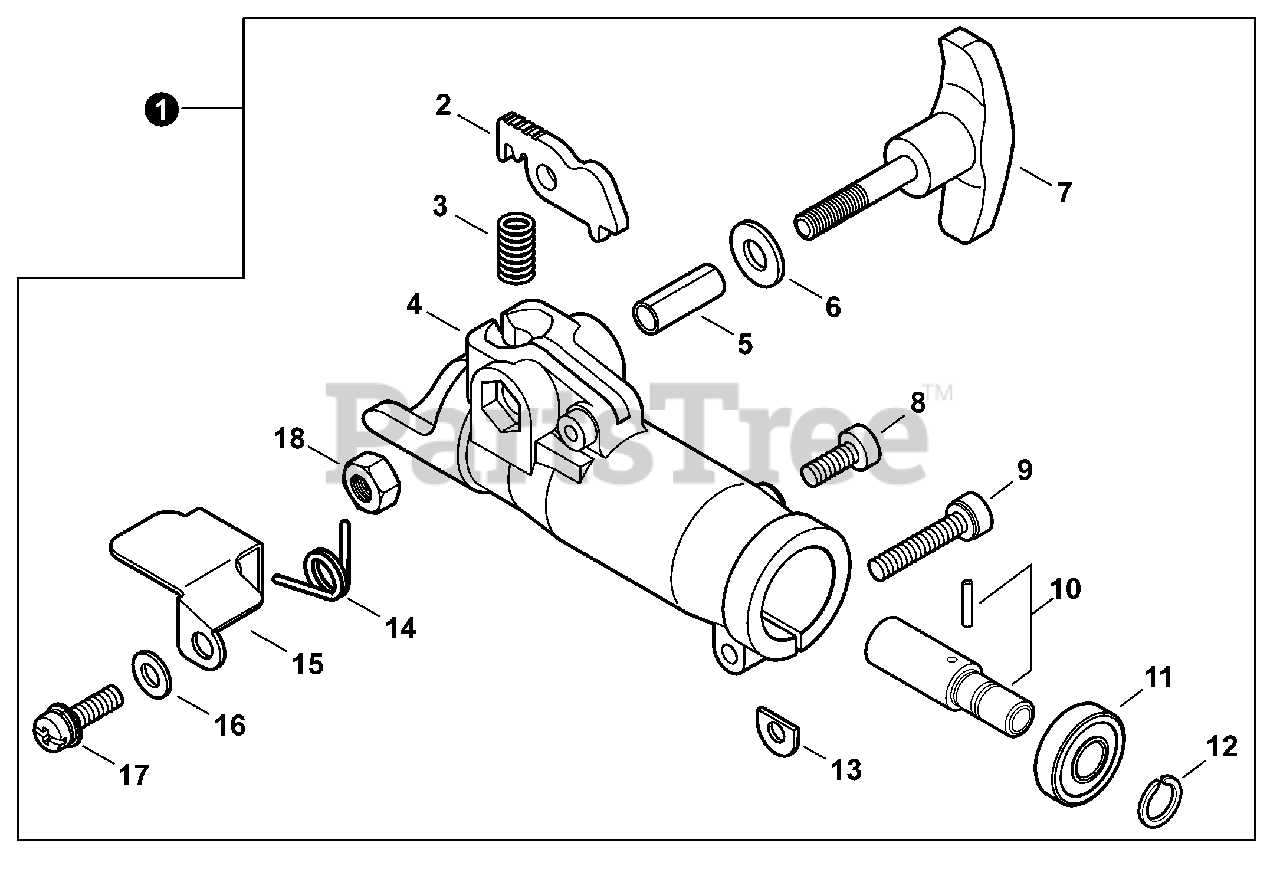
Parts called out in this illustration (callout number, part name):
1	COUPLER ASSY
3	SPRING, COIL
4	HOUSING, COUPLER
5	SLEEVE, KNOB 6×L= 22
6	WASHER 6
7	KNOB, COUPLER SCREW
8	BOLT 5×12
9	BOLT M5×25
10	SHAFT, COUPLER
11	BEARING, BALL 609ZZ
12	RING, SNAP Ø9
13	D-WASHER
14	SPRING, TORSION
15	PROTECTOR, LATCH
16	WASHER 5
17	SCREW M5×12
